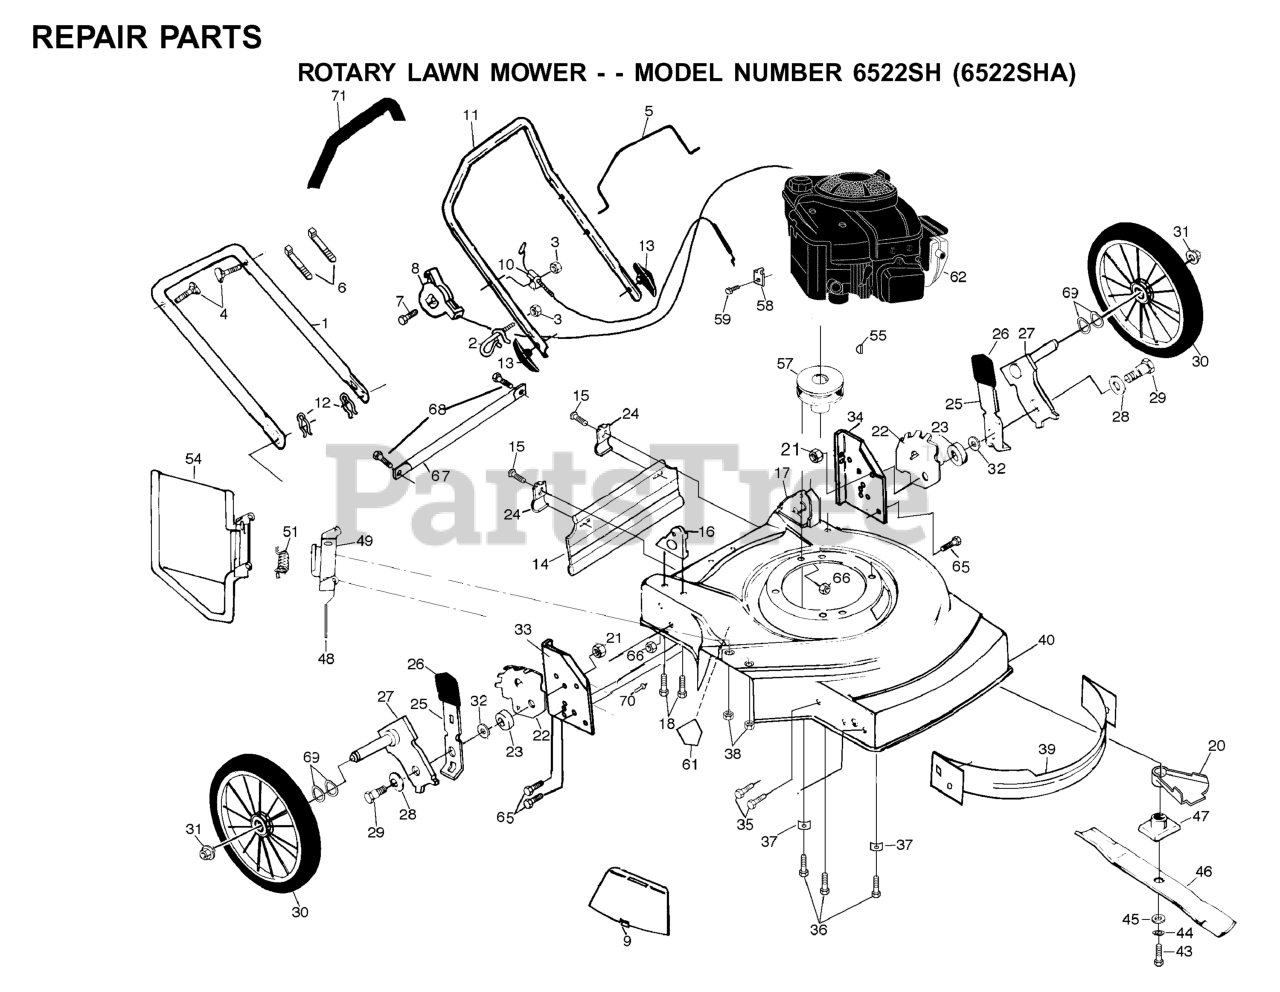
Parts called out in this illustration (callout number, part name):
1	LOWER HANDLE
3	NUT
4	HANDLE BOLT
6	TIE GUIDE
7	SCREW 1/4-20 X 2.12
8	THROTTLE CONTROL
9	REPL BY 532 12 54-20
10	CABLE.MZR.51.RT.SP./PU.
11	UPPER HANDLE
12	HAIRPIN COTTER
13	HANDLE KNOB
14	REAR SKIRT
15	TAPPING SCREW
16	HANDLE BRACKET ASM. RH
17	HANDLE BRACKET ASM. LH
18	SCREW.5/16-18X3/4
20	DEBRIS SHIELD
21	LOCKNUT PM
22	WHEEL ADJ BRKT
23	RP SPACER HT ADJ
24	BRACKET DEFL PM
25	SELECTOR SPRING
29	BOLT
31	HEX FLANGE LOCKNT
32	WASHER.FLAT.1/2
35	SCREW 1/4X20
36	BOLT 3/8-16X1-1/8
37	WASHER.ENGINE.BZP
38	NUT
39	FRONT BAFFLE KIT
43	SCREW, HEX HD 3/8-24 X 1-3/8
44	LOCKWASHER
45	WASHER,HARDEN
47	BLADE ADAPTOR
48	ROD.HINGE.COMBI-C
49	BRACKET PM
54	DISCHARGE GUARD
55	HI PRO KEY PM WSL
57	ENGINE.PULLEY.FWG
58	WASHER
59	SCREW.HEX.HEAD.WASHER.10-16
61	DECAL HYT
66	LOCKNUT PM
69	WAVE WASHER
70	RIVET BLIND
71	GRIP.HANDLE.FOAM
